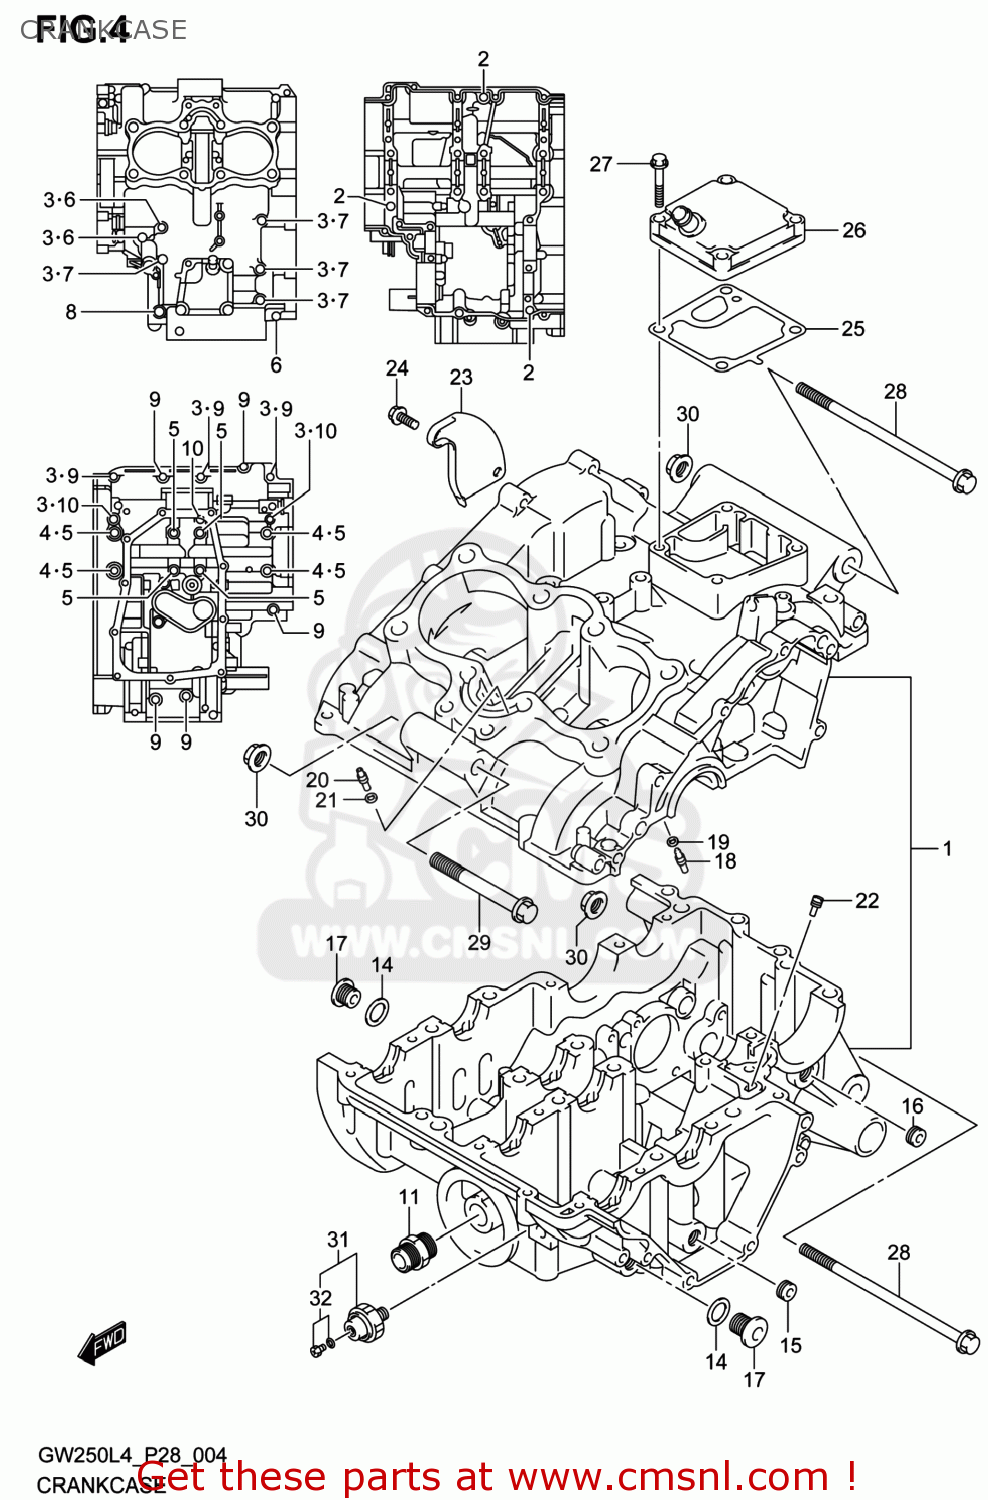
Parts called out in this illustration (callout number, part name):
1	CRANKCASE SET
2	PIN
3	GASKET(5.8X13X1.8) (NAS)
4	GASKET(8.2X14X1) (NAS)
5	BOLT(8X105)
6	BOLT
7	BOLT
8	BOLT
9	BOLT
10	BOLT
11	UNION,OIL FILTER STAND
12	BEARING,CRANK THRUST(YELLOW)
13	BEARING,CRANK THRUST(PINK)
14	GASKET(13.8X18.8X4.8) (NAS)
15	PLUG,OIL GALLERY
16	PLUG(1/4PT,H:7.5)
17	PLUG,14X12
18	JET,PISTON COOLING
19	O RING(D:1.2,ID:4)
20	JET,OIL GALLERY CYLINDER
21	O RING(D:1.2,ID:4)
22	JET,T/M COOLING
23	PLATE,OIL SEPARATOR
24	BOLT
25	GASKET,BREATHER COVER(NA) (NAS)
26	COVER,BREATHER
27	BOLT
28	BOLT(10X155)
29	BOLT(10X85)
30	NUT
31	SWITCH ASSY,OIL PRESSURE
32	BOLT,OIL PRESSURE SWITCH
